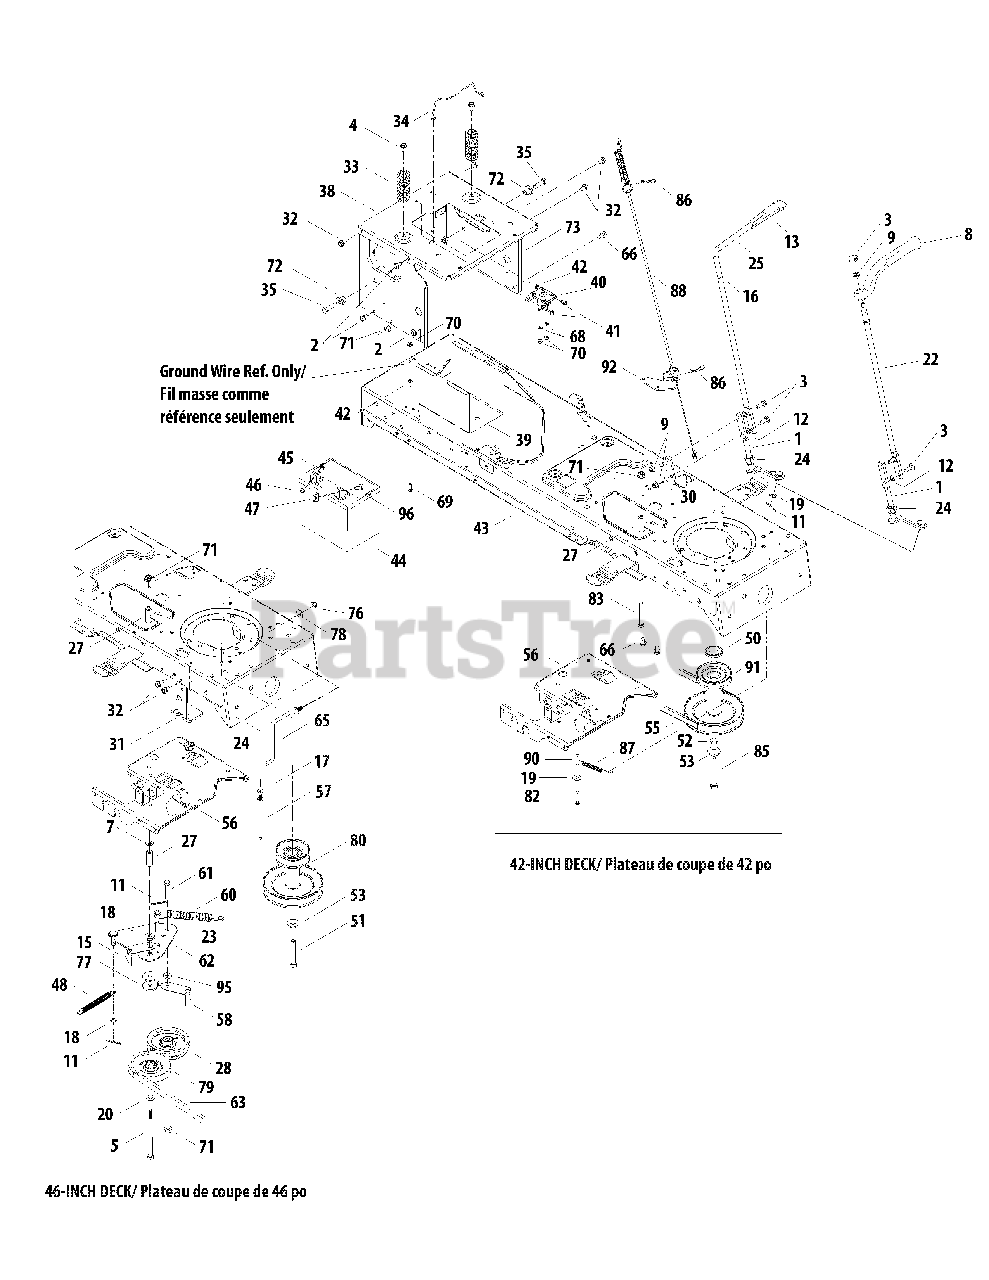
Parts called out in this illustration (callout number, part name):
1	PTO Engage lever Assembly
2	Hex Hd. TT Scr. 5/16-18 x .625
3	Carriage Bolt 5/16-18 x 1.00" Lg
4	Hex Wash HD AB Tap Scr 5/16-12 x .75
5	Hex Cap Screw, 3/8-16 x 1.5
7	Push Nut Bolt Retainer
9	Hex Flange L-Nut 5/16-18
11	Cotter Pin 1/8" Dia x 1.00
12	Push Speed Nut
16	Flat Washer .510 ID x .75 OD x .033
17	L-Wash 5/16 ID
18	Flat Washer .385 ID x .62 OD x .06
19	Flat Washer .28 ID x .74 OD x .063
20	Flat Washer .385 ID x .87 OD x .06
21	Cap Plug .812 dia.
22	Deck Engagement Handle
23	Shoulder Spacer
24	Hex Slpit Flange Bearing .50 ID
25	Deck Engagement Handle
27	Spacer .385 ID x .635 OD x 1.54
28	Flat Idler Pulley 3.5 OD
32	Hex Wash HD AB Tap Scr 5/16 x .75
33	Compression Spring 1.28 x 3.125
34	Battery Retainer Rod
35	Hex Bolt 3/8-16 x 1.25
41	Hex Wash S-Tapp Scr 1/4-20 x .50
42	Ext. L-Washer 1/4 ID
45	Carriage Bolt 1/4-10 x .75
46	Sems Hex Nut 1/4-20
47	Wing Nut 1/4-20 Thd.
48	Extension Spring .50 x 5.0
50	Spacer 1.010 x 1.4 x .825
51	Hex Bolt 7/16-20 x 2.75 Gr. 5
52	Flat Washer .450 x 1.25 x .164
53	Lockwasher 7/16 ID
55	PTO Belt (w/42" deck)
57	Keeper Pin 5/16 x 4.75
58	Belt Guard
60	Extension Spring .75 x 6.75
61	Hex TT Sems Scr. 3/8-16 x 1.5
63	PTO Belt (w/46" Deck)
65	Belt Keeper Rod
66	Hex Wash HD S-Tapp Scr 5/16-18 x .50
68	L-Wash 1/4 ID
69	Thd Forming Scr. 1/4-20 x .75 Lg.
70	Hex L-Flanged Nut 1/4-20 Gr. F Nylon
71	Flange Lock-Nut 3/8-16 Gr. F Nylon
72	Shoulder Spacer .38 x 1.0 x .70
78	Cupped Washer .345 ID x .88 OD x .060
79	4" Dia. V-Idler
80	Engine Pulley 3.39 x 6.12 Dia 46" Trans.
80	Engine Pulley 3.56 x 6.12 Dia 46" Hydro
82	Hex Bolt 1/4-20 x 1.5
83	Hex Cap Screw, 3/8-16 x 2.5
85	Hex Bolt 7/16-20 x 3.25 Gr. 5
86	Internal Cotter Pin
87	Extension Spring .38 OD x 3.9 Lg.
88	Deck Engage Cable
90	Spacer .260 x .375 x 1.030 Lg.
91	Engine Pulley 3.39 x 6.12 dia 42" Trans
91	Engine Pulley 3.56 x 6.12 Dia 42" Hydro
96	Shoulder Screw, 1/4-20
